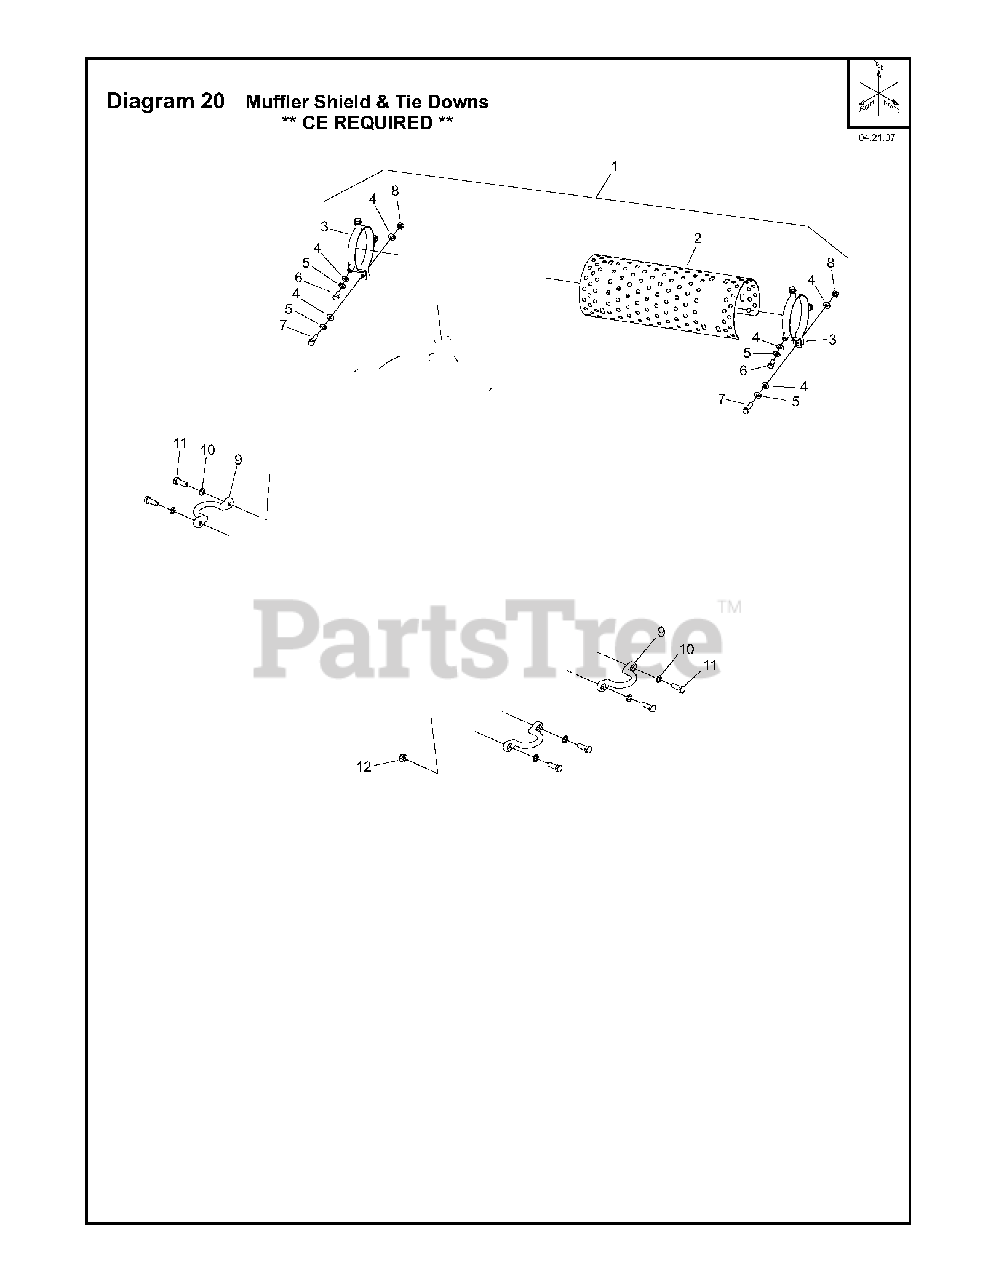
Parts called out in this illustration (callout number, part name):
1	KIT: MUFFLER SHIELD B/M
2	SHIELD. MUFFLER - BLACK
4	HHCS. M8 x 1.25 x 16 DIN933 ZP
5	WASHER
6	LOCKWASHER. STAR EXTERNAL M-8
8	NUT
9	*CHAIN LOOP. TIEDOWN - Z/P
10	LOCKWASHER. EXTERNAL STAR M10
11	HHCS. M10 x 1.5 x 30 DIN931 ZP
12	LOCKNUT. FIBER M10 DIN 985
